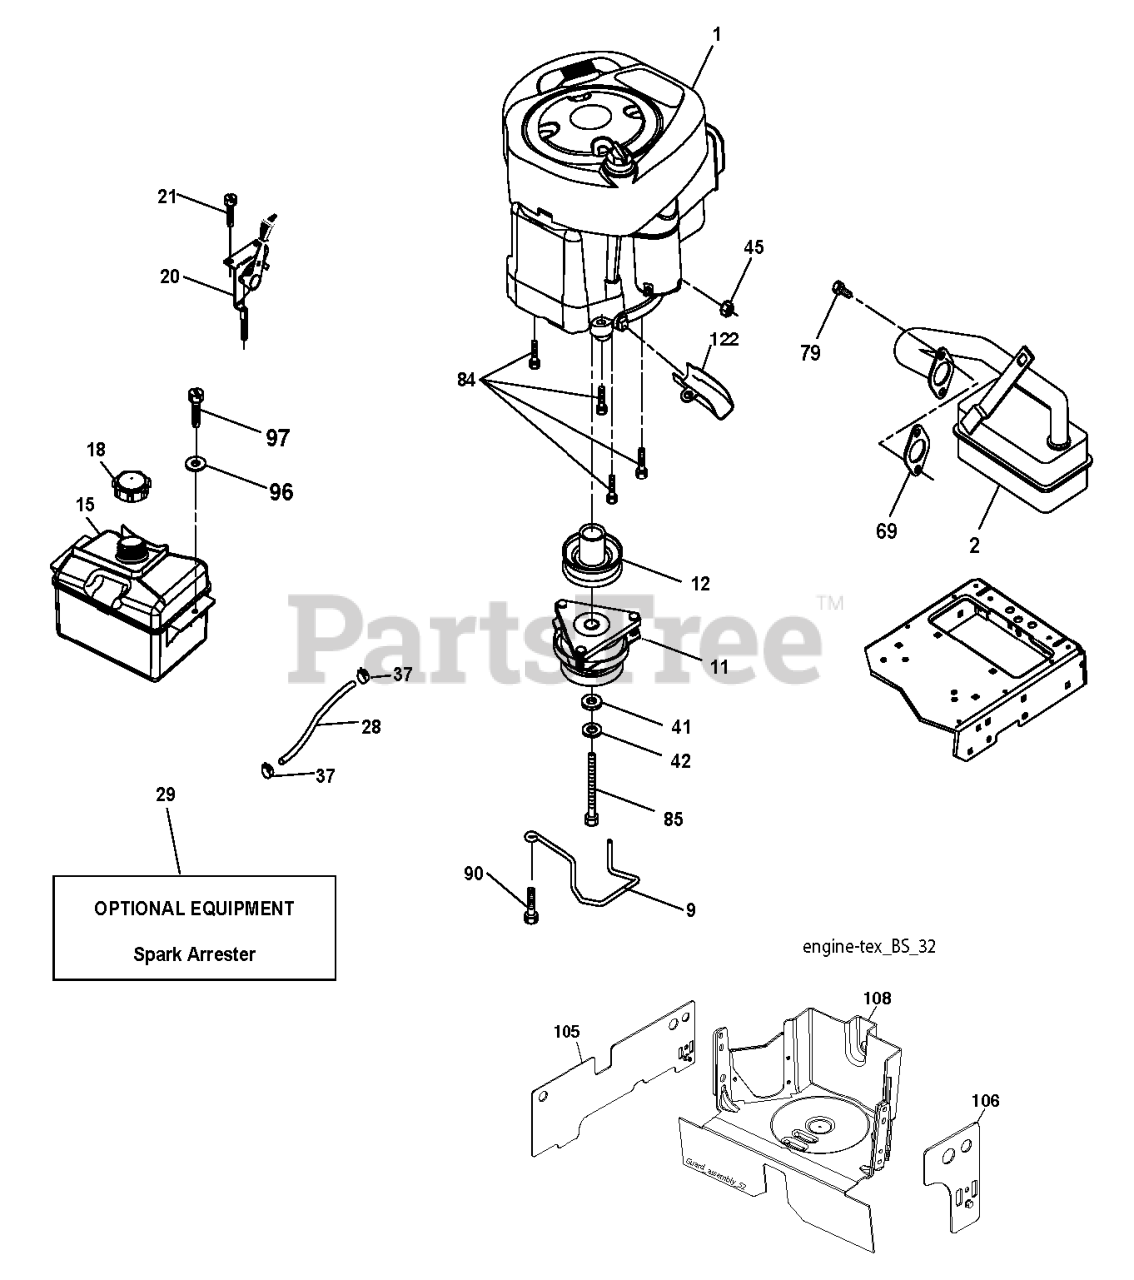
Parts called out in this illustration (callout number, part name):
2	MUFFLER.B&S.MODEL.21.11HP.OHV
9	KEEPER.BELT.ENGINE.3.25 (3 2)
11	RB.CLUTCH.OGURA.4.4.PD
12	PULLEY.ASM.ENG.OGURA.3
15	RP TANK FUEL FRT 1.5 GAL
18	CAP ASM.FUEL.2.25"FR.
20	CONTROL.TH/CK.C.
21	SCREW.#10 X 0.750.BOS
28	LINE.FUEL.20
29	KIT.SPARK ARRESTOR 794945 B&S
37	HOSE CLAMP
42	LOCKWASHER
45	NUT
69	REPL BY 532 27 22-93
79	SCREW.SOCKET HD.5/16-1
84	SCREW.3/8-16
85	BOLT HEX 7/16-20X4-1/4"
90	SCREW 3/8-16X1
97	SCREW HEXWSHR 1/4-20X3/4
105	SHIELD LEFT
106	SHIELD SIDE
108	COVER PULLEY
122	EXTENSION DRAIN OIL
